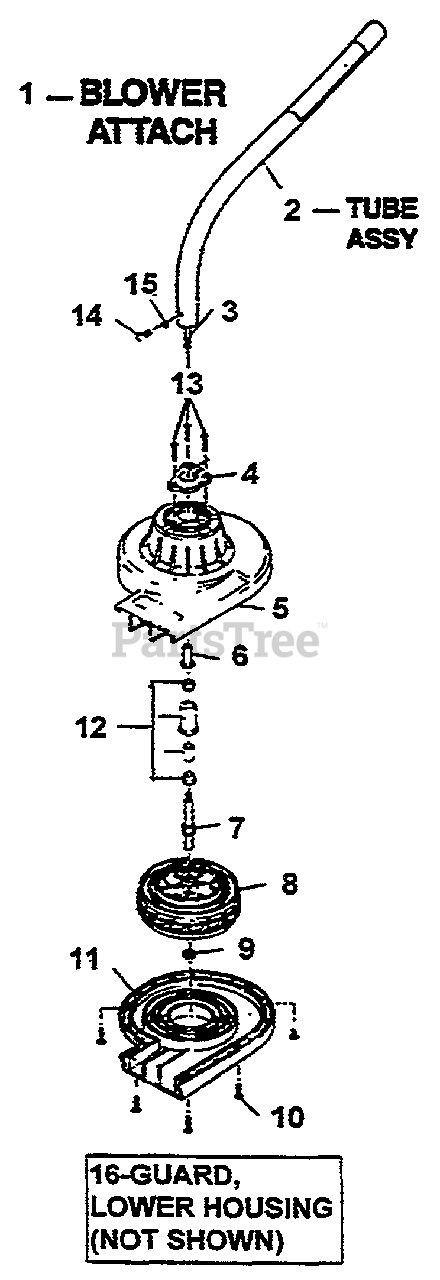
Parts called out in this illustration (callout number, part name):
1	BLOWER ATTACHMENT
2	TUBE ASSY
3	FLEX CABLE
5	UPPER HOUSING
6	ARBOR ADAPTER
7	ARBOR SHAFT
10	SCREW
11	LOWER HOUSING
12	ARBOR BUSHING ASSY
13	SCREW
16	GUARD, LOWER HOUSING
